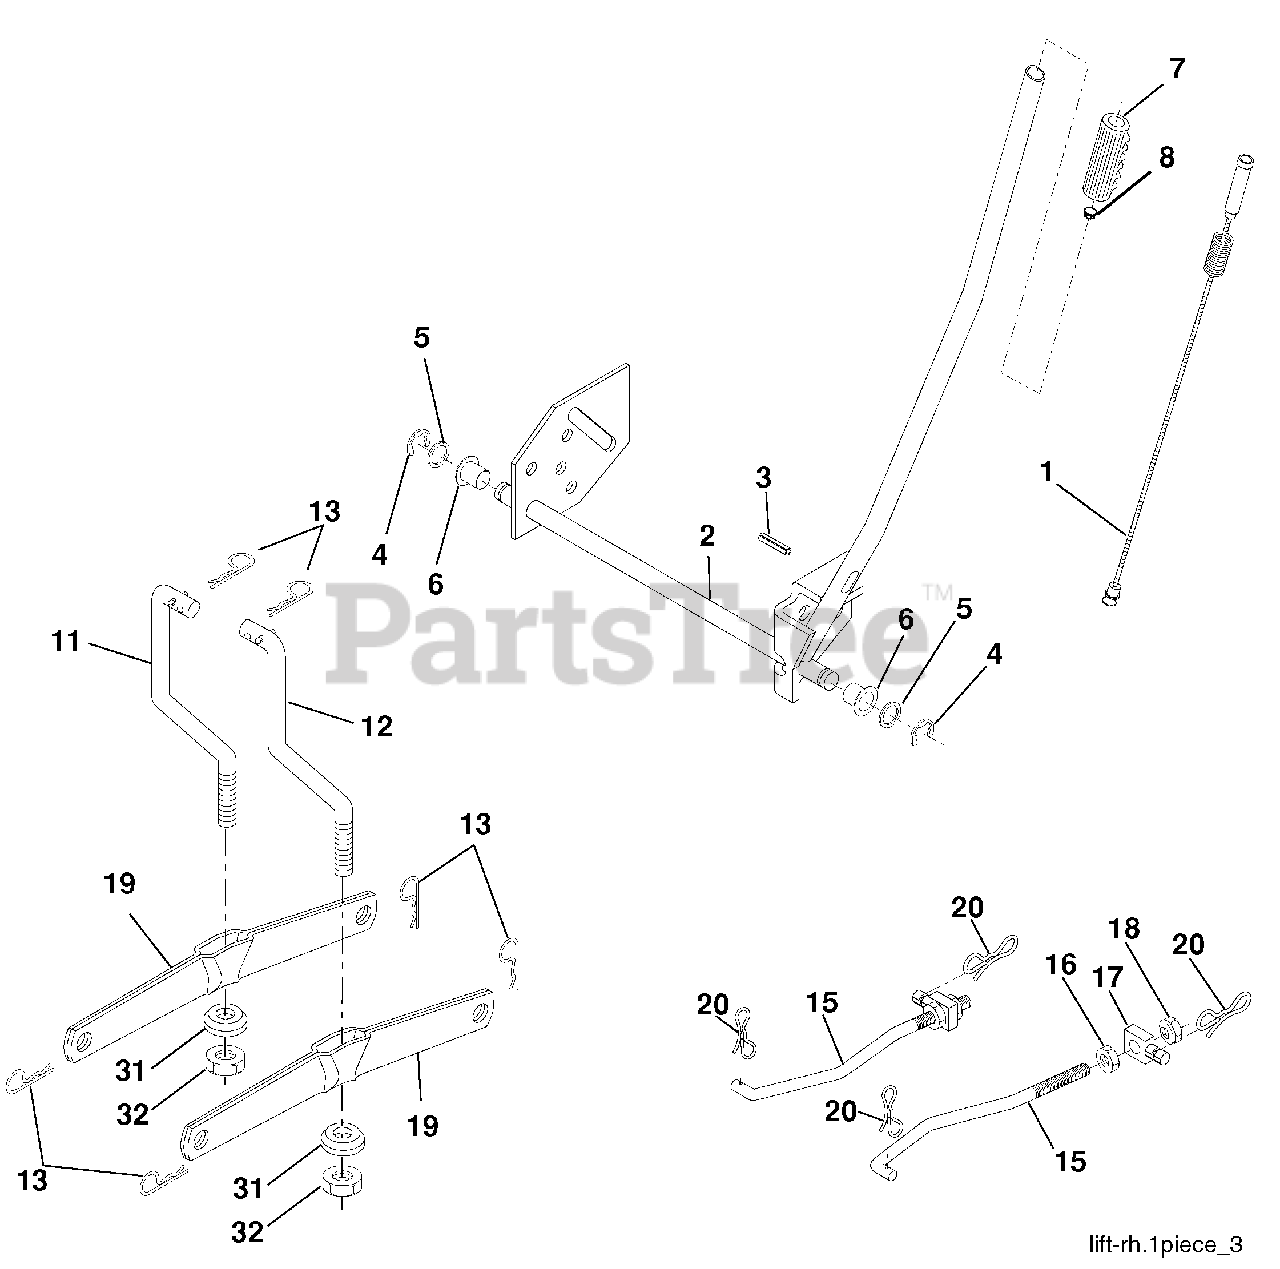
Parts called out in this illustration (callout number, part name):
1	Wire Asm. Inner/Sprg. w/Plunger
2	Shaft Asm. Lift RH
3	Pin Groove 1 500 Zinc
4	E Ring #5133-62
5	Washer 21/32 x 1 x 21 Ga.
6	Bearing Nylon Blk. 629 Id
7	Grip Handle
8	Button Plunger Red
11	Link Lift LH Fixed Length
12	Link Lift RH Fixed Length
13	Retainer Spring
15	Link Front
16	Nut Jam Hex 1/2-13 unc
17	Trunnion
18	Nut Lock w/Wsh. 1/2-13 unc
19	Arm Suspension Rear
20	Pin Cotter 7/16 Bow Tie Lock
31	Bearing Pvt. Lift
32	Nut Crownlock 3/8-24
